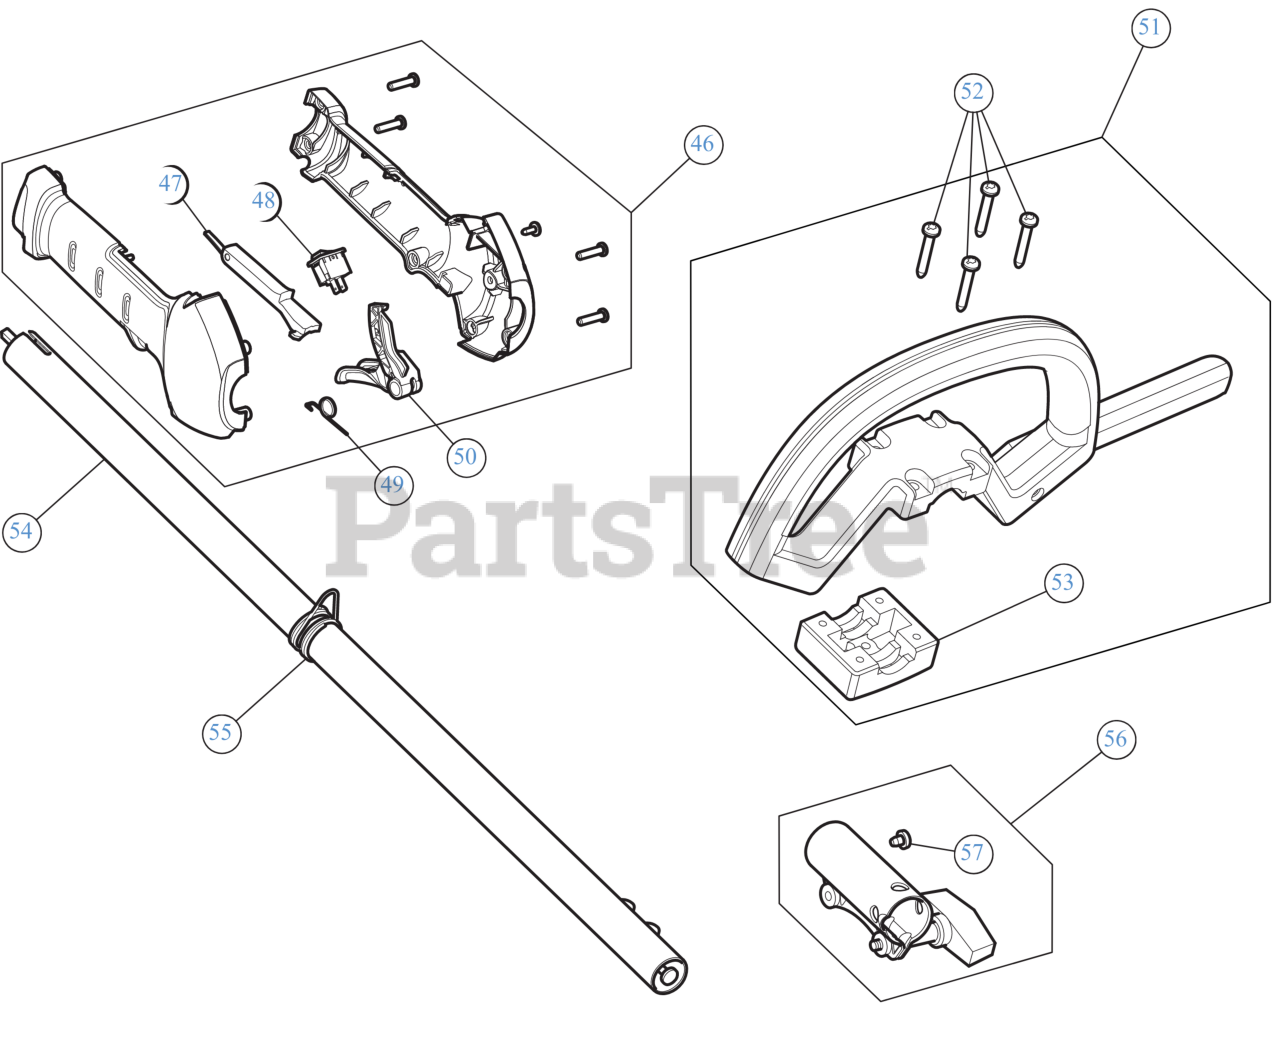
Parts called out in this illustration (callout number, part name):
46	THROTTLE HOUSING ASSEMBLY
47	LEVER LOCK OUT
48	SW, MOMENTARY ON/O
49	TRIGGER SPRING
50	THROTTLE TRIGGER
51	HANDLE:D
53	HANDLE BASE
54	BOOM ASSEMBLY UPR
55	CLAMP-SHOULDER STR
56	CLICK LINK
57	SCREW, 10-32X.250 TA
